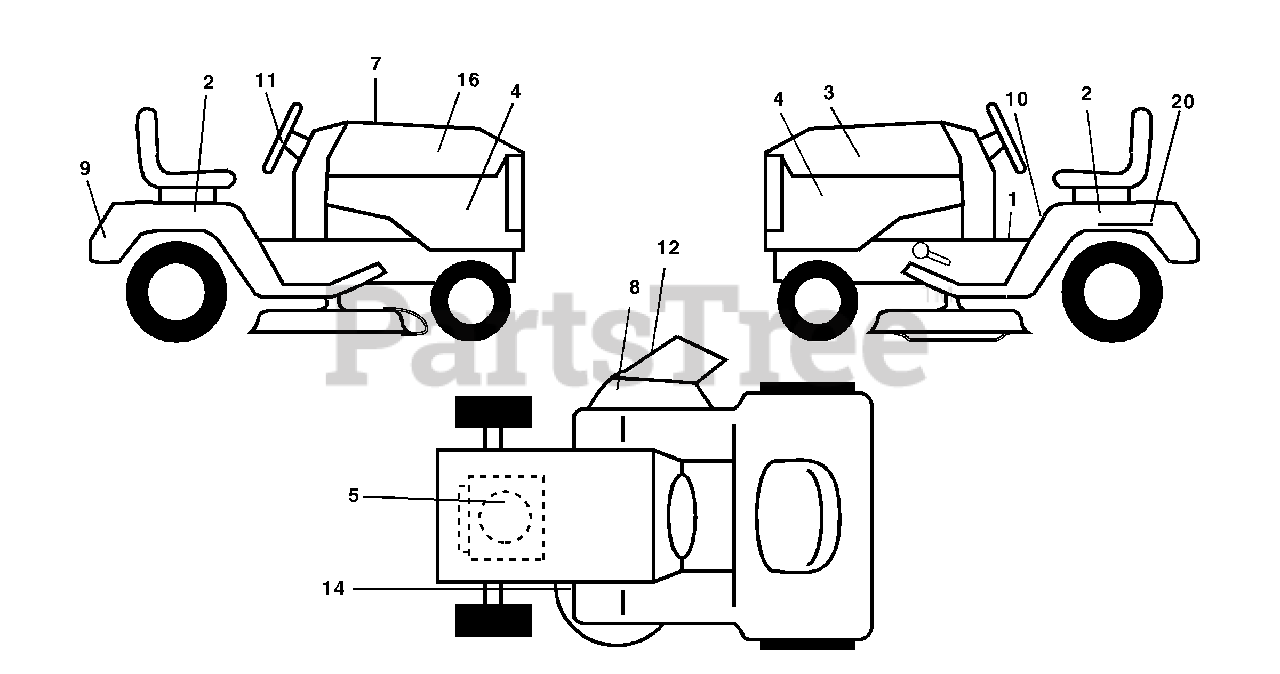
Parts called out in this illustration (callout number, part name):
1	Decal Oper
2	Decal Fender Auto
3	Decal Hood LH
4	Decal Side Panel Logo
5	Decal HP Engine
7	Decal Replacement Parts
8	Decal Deck "B" 42"
9	Decal Fender Logo
10	Decal Fender Danger E/F
11	Decal Ins Strg Whl
12	Decal Mower Warn Keep Hand Away
14	Decal V-Belt Schematic
16	Decal Hood Rh
20	Decal Bat Dan/Psn
